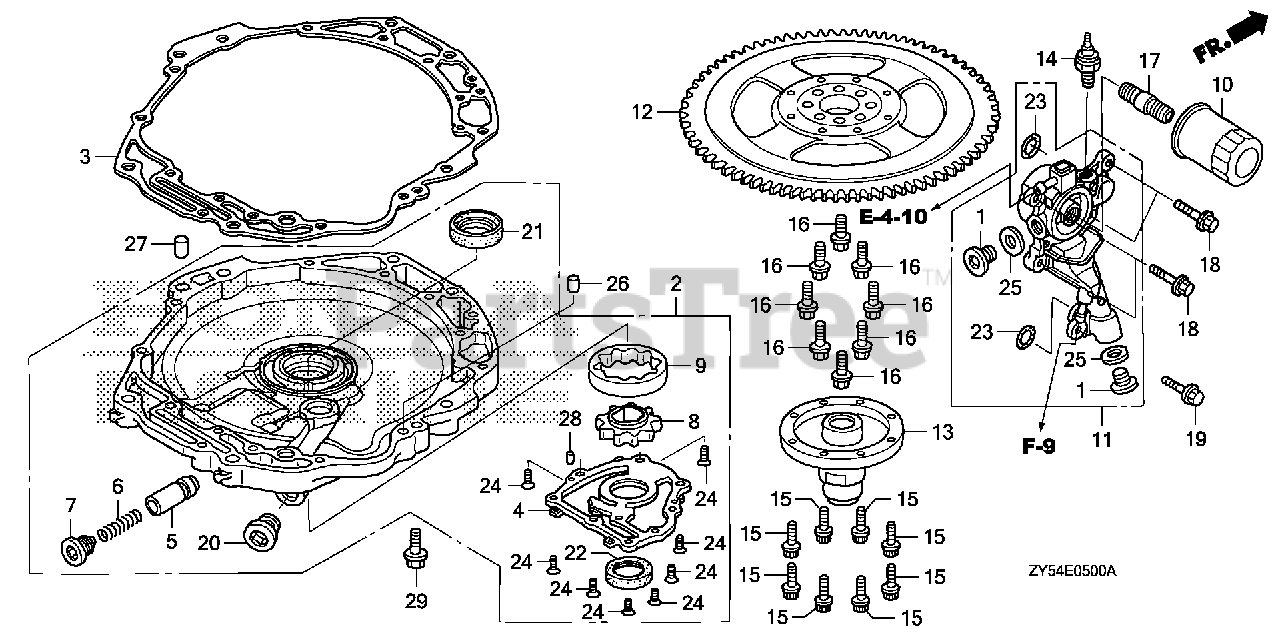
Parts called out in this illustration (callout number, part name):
1	BOLT, SEALING (20MM)
2	PUMP ASSY., OIL *NH8* (DARK GRAY)
3	GASKET, OIL PUMP BODY
4	COVER, OIL PUMP
5	VALVE, RELIEF
6	SPRING, RELIEF VALVE
7	BOLT, SEALING (18MM)
8	ROTOR, OIL PUMP (INNER)
9	ROTOR, OIL PUMP (OUTER)
10	FILTER, OIL (FILTECH TOYO ROKI) (SOLD IN MULTIPLES OF 30)
10	FILTER, OIL
10	FILTER, OIL (FILTECH TOYO ROKI) (SOLD INDIVIDUALLY)
11	FLANGE, OIL FILTER *NH8* (DARK GRAY)
12	FLYWHEEL *TBLACK* (BLACK)
13	BOSS, FLYWHEEL
14	SWITCH ASSY., OIL PRESSURE
15	BOLT, SPECIAL (8MM)
16	BOLT, FLANGE (12MM)
17	HOLDER, OIL FILTER
18	BOLT, FLANGE (6X25)
19	BOLT, FLANGE (6X20)
20	BOLT, SEALING (22MM)
21	OIL SEAL (46X60X9)
22	OIL SEAL (31X46X7) (NOK)
23	O-RING (22.5X2.4)
24	SCREW, FLAT (6X16) (YAMADA)
25	WASHER, DRAIN PLUG (20MM)
26	PIN A, DOWEL (10X16)
27	PIN A, DOWEL (14X20)
28	ROLLER (5X8)
29	BOLT, FLANGE (8X32)
